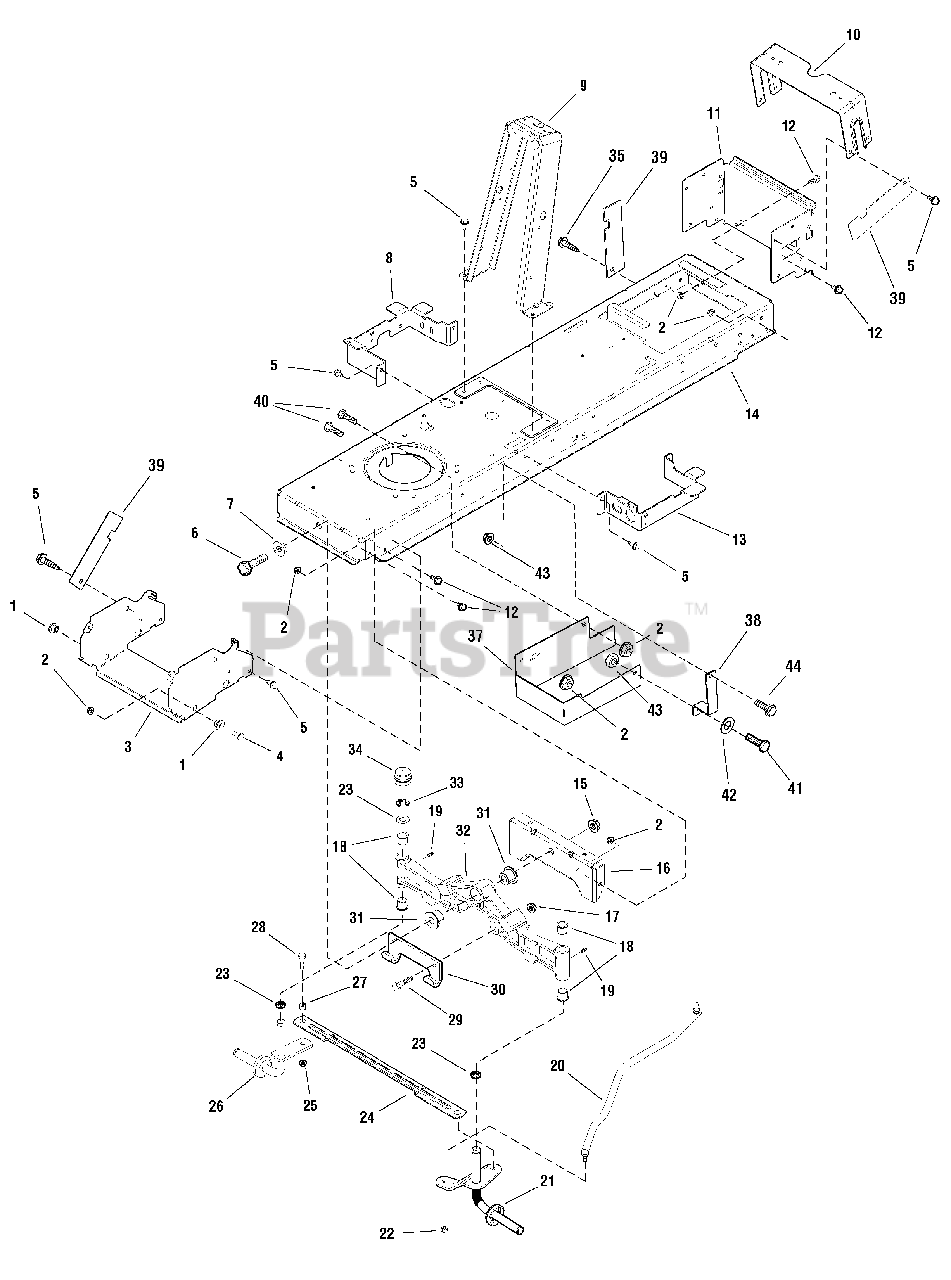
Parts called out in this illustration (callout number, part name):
1	PIVOT, Hood Powdered Metal
2	NUT, Hex, Flange Whizlock, 5/16-18
3	SUPPORT, Muffler, Hood 14GA
4	BOLT, Carriage, Short Neck, 5/16-18 x 1
5	SCREW, Taptite, 5/16-18 x 5/8
6	CAPSCREW, Hex Head, 5/8-11 x 3-1/4 G5
7	WASHER, Flat, 5/8
8	SUPPORT, Front Footrest RH
9	TOWER, 12GA
10	SUPPORT, Seat Deck 12GA
11	SUPPORT, Rear Frame 12GA
12	CAPSCREW, Hex Head, Flange Whiz Lock, 5/16-18 x 3/4
13	SUPPORT, Front Footrest LH
14	FRAME, 12GA
15	NUT, Hex Flange Two-Way Lock, 5/8-11
16	PLATE, Axle Support
17	LOCKNUT, Hex, Flange, 7/16-14
18	BUSHING, Nylon, 3/4 Diameter
19	FITTING, Zerk
20	LINK, Drag
21	SPINDLE & ARM ASSEMBLY, LH
22	NUT, Hex Nylock 3/8-24
23	WASHER, 3/4
24	ROD, Tie
25	NUT, Hex, Flange, Locking, 3/8-16
26	SPINDLE & CUP ASSEMBLY, RH
27	BUSHING, Powdered Metal
28	CAPSCREW, Hex Head, 3/8-16 x 1-1/4, .141 Thread G5
29	CAPSCREW, 7/16-14 x 1.5
30	HOOK, "J"
31	BUSHING, Axle Pivot Powdered Metal
32	AXLE, Front Iron Casting Machined
33	RING, Klipring Extension
34	CAP, Hub
35	SCREW, Taptite 5/16-18 x 3/4
37	GUARD, Clutch
38	SUPPORT, Guard
39	GUARD, Pulley Rear
40	CAPSCREW, Hex 5/16-18 x 3/4
41	CAPSCREW, Hex 1/4-20 x 1/2
42	WASHER, 1/4
43	NUT, Hex Lock 1/4-20
44	CAPSCREW, 1/4-20 x 3/4
